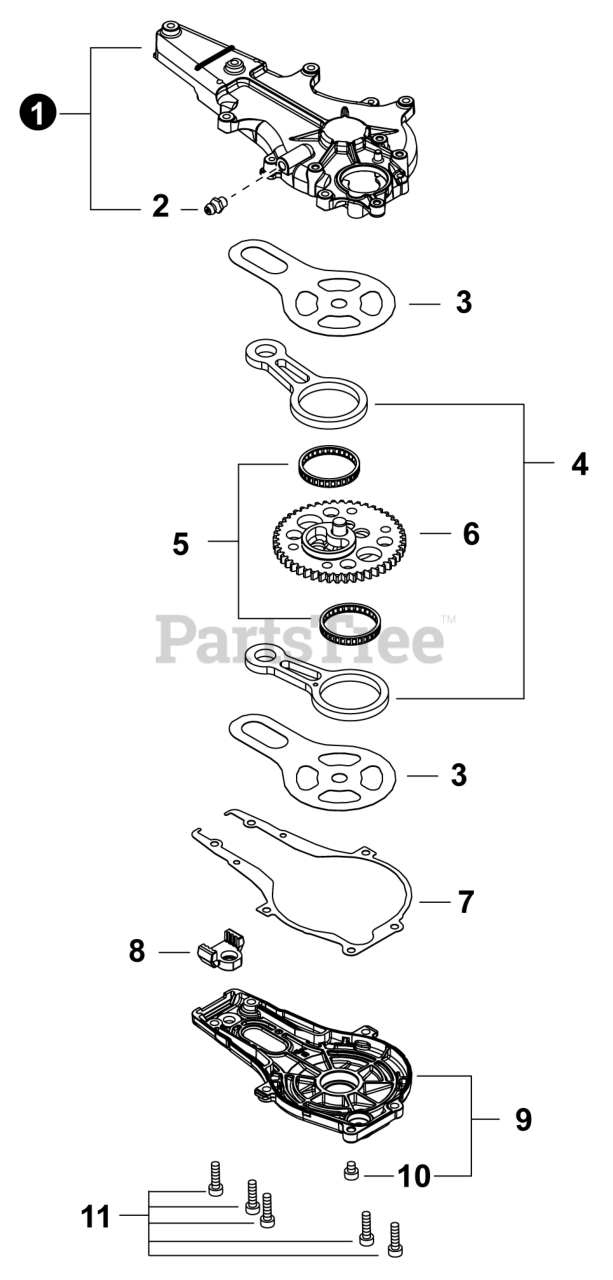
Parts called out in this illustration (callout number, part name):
1	GEAR CASE ASSY
2	FITTING, GREASE
3	PLATE, SIDE
4	ROD, CONNECTING
5	BEARING, NEEDLE 30
6	GEAR, SPUR
7	GASKET, GEAR CASE
9	COVER ASSY, GEAR CASE
10	BOLT 5x6
11	BOLT, TORX 4x16
